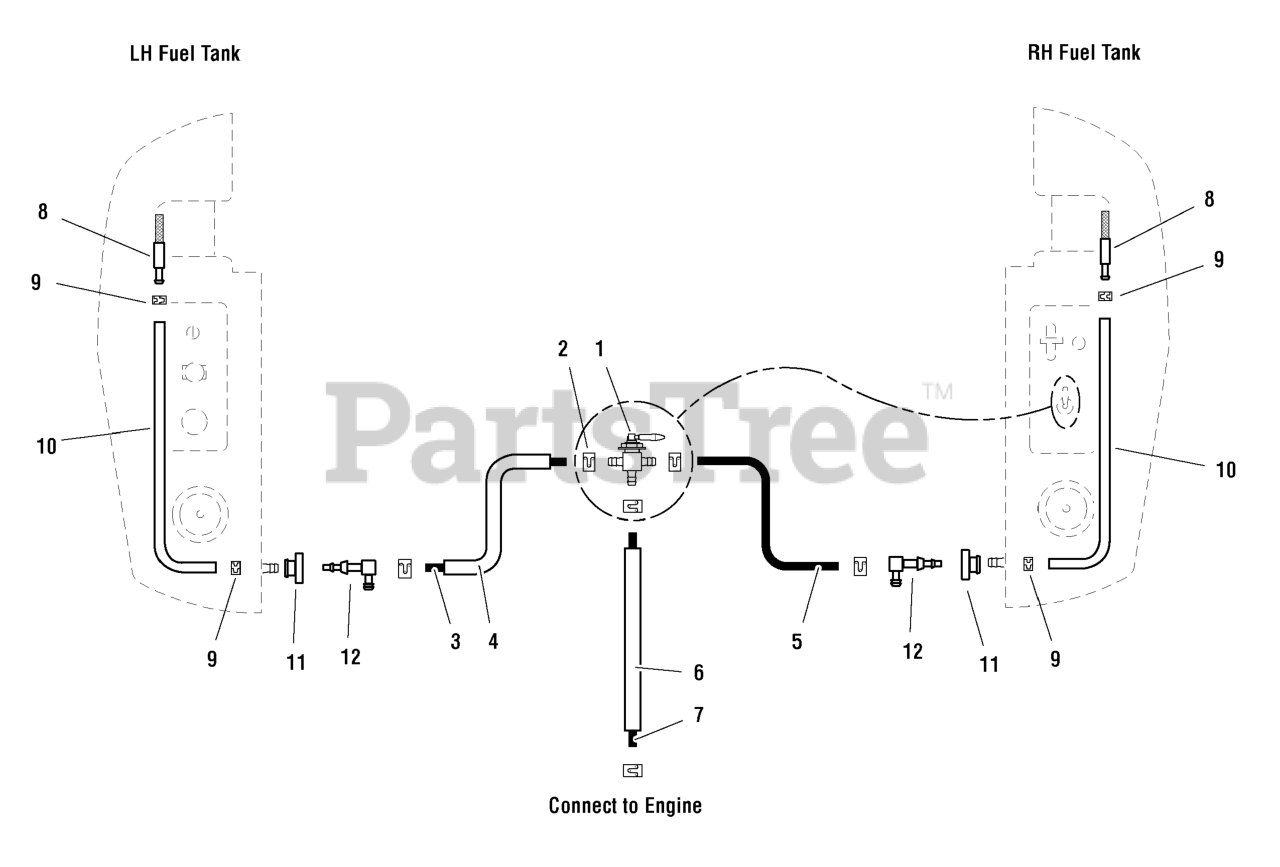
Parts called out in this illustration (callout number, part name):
1	VALVE, Fuel Shut Off
2	CLAMP, Hose
3	1/4" Fuel Line, 45" Long
4	WIRE LOOM, 43"
5	1/4" Fuel Line, 6-1/2" Long
6	WIRE LOOM, 40"
7	1/4" Fuel Line, 42" Long
8	SEE HOSE ASSEMBLY
9	SEE HOSE ASSEMBLY
10	ASSM, FUEL HOSE, 20"
11	BUSHING-FUEL TANK RED RUBBER
12	ELBOW FITTING
